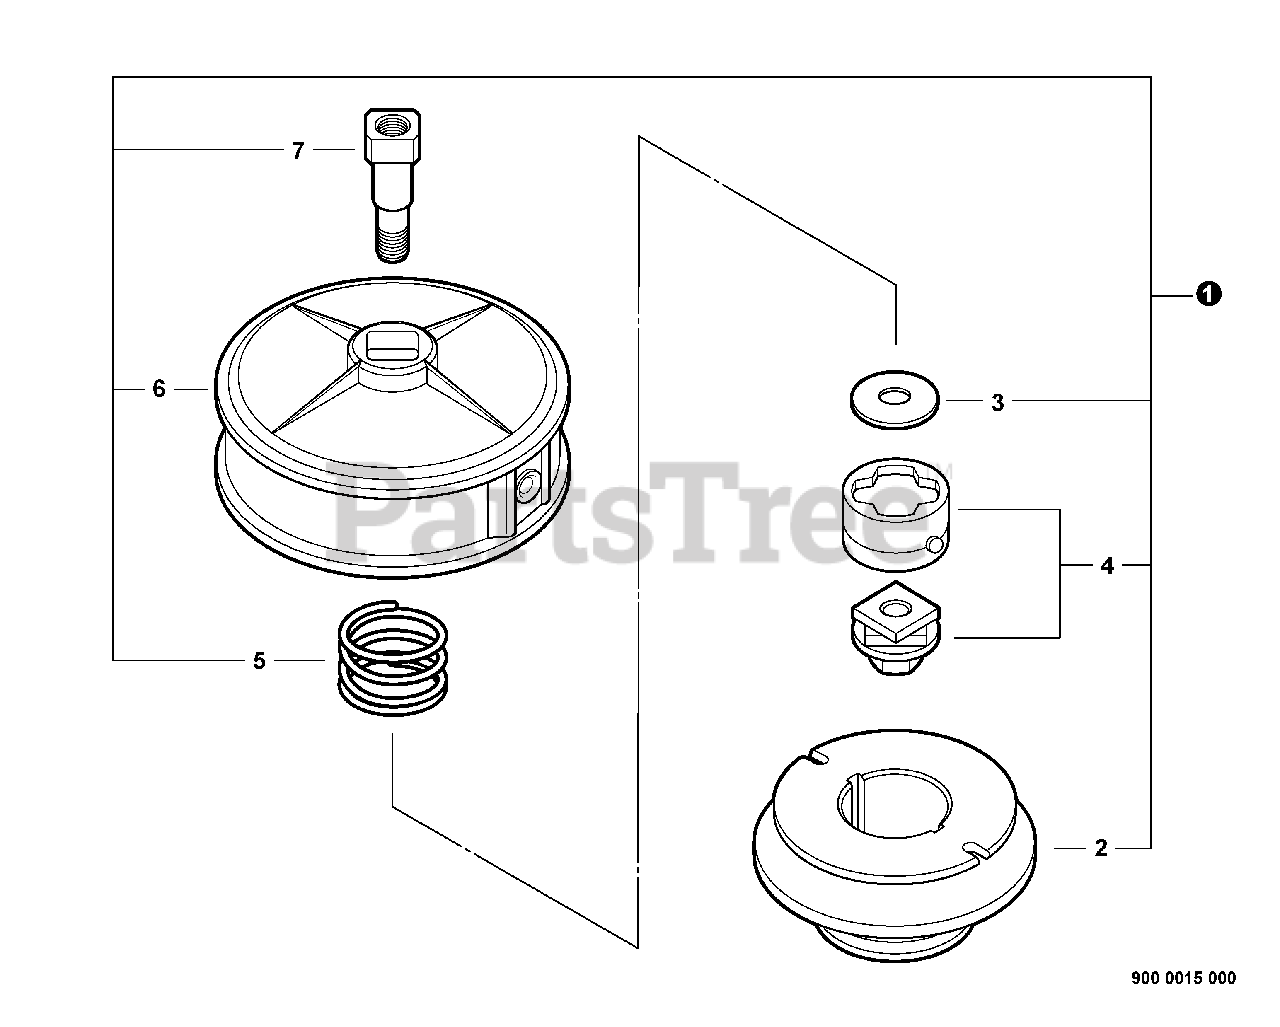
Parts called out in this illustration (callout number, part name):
1	TRIMMER HEAD, SRM ECHOMATIC®
2	SPOOL
3	WASHER
4	CAM ASSY
5	SPRING
6	HOUSING, SPOOL
7	STUD, ARBOR M10×1.25 LH
